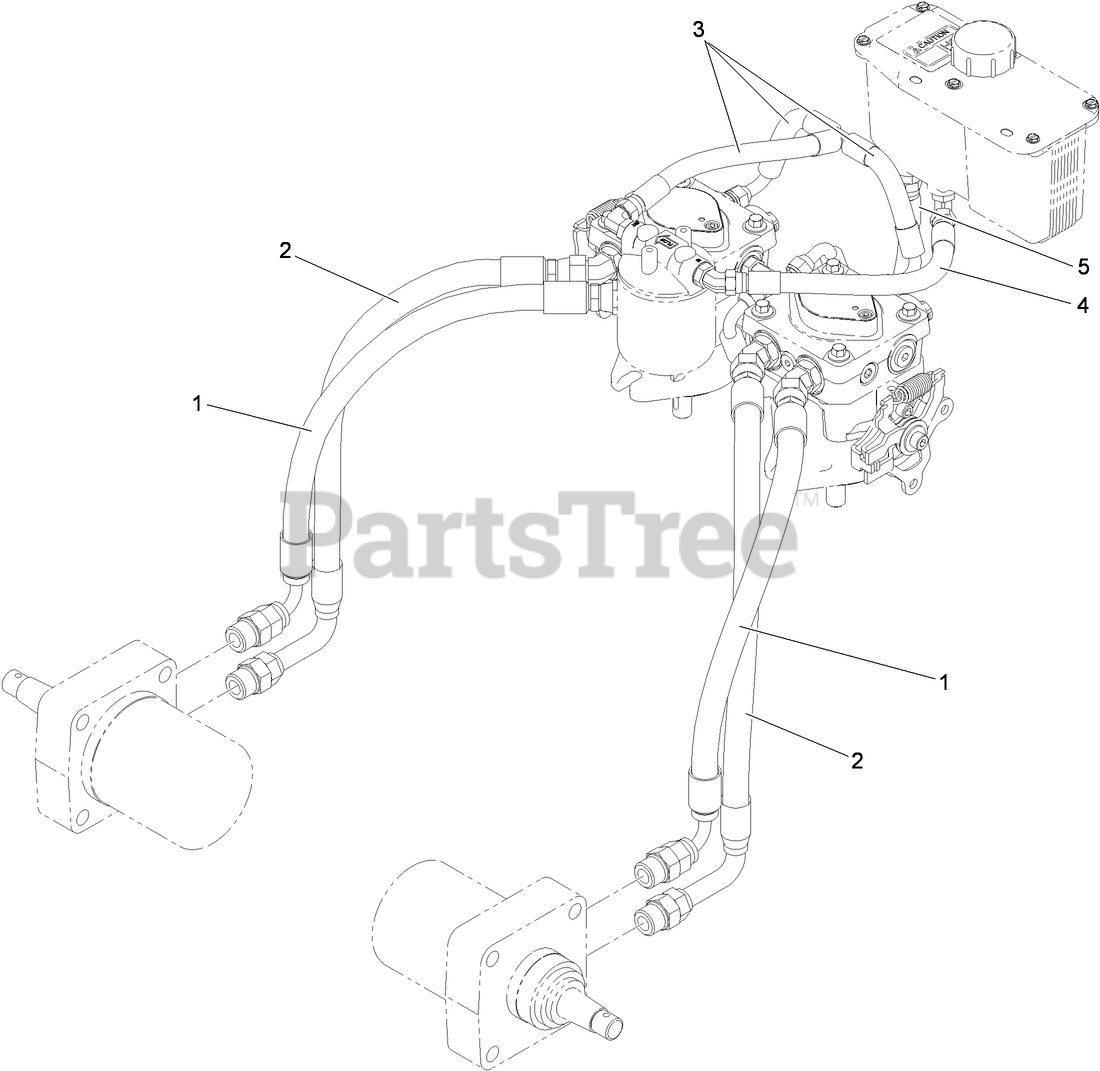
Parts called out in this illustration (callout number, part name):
1	HYD HOSE ASM
2	HYD HOSE ASM
3	HYD HOSE ASM
4	HYD HOSE ASM
5	HYD HOSE ASM
